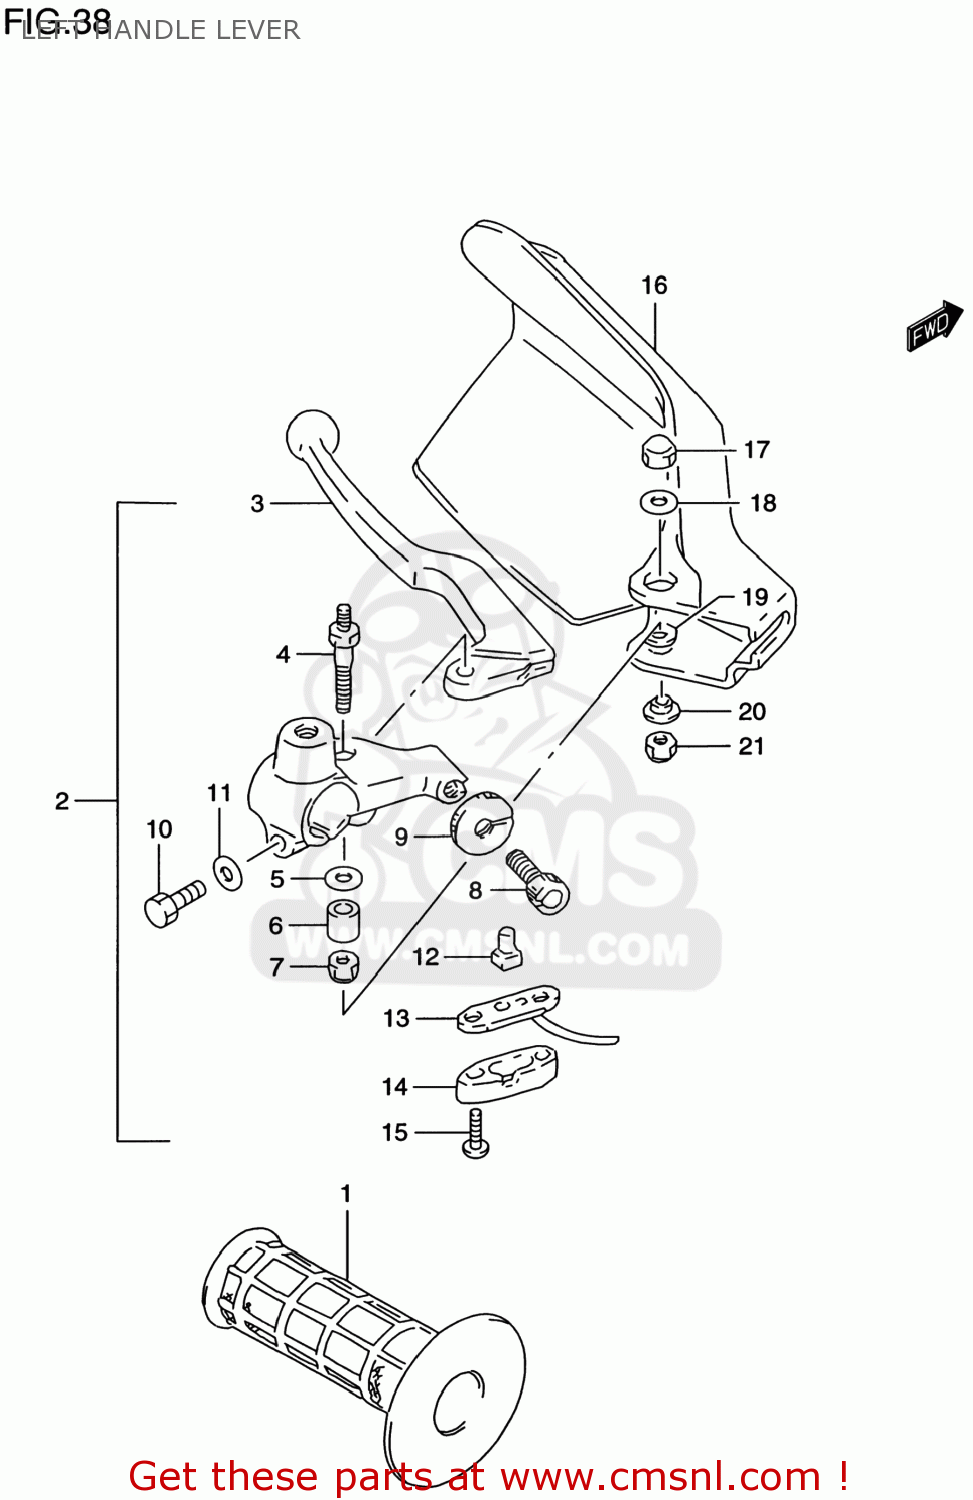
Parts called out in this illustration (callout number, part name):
1	GRIP,L
2	LEVER ASSEMBLY,CLUTCH
3	LEVER,CLUTCH
4	BOLT,CLUTCH LEVER PIVOT
5	WASHER
6	SPACER,LEVER SET
7	NUT
8	ADJUSTER,CABLE
9	NUT,CABLE ADJUSTER LOCK
10	BOLT
11	WASHER
12	CONTACT,SWITCH
13	HARNESS ASSY,WIRE
14	COVER,FR BK TERMINAL BASE
15	SCREW
16	COVER,KNUCKLE,LEFT
17	NUT
18	WASHER(6.5X20X1.6)
19	WASHER(6.5X16X1.2)
20	WASHER
21	NUT 6MM
